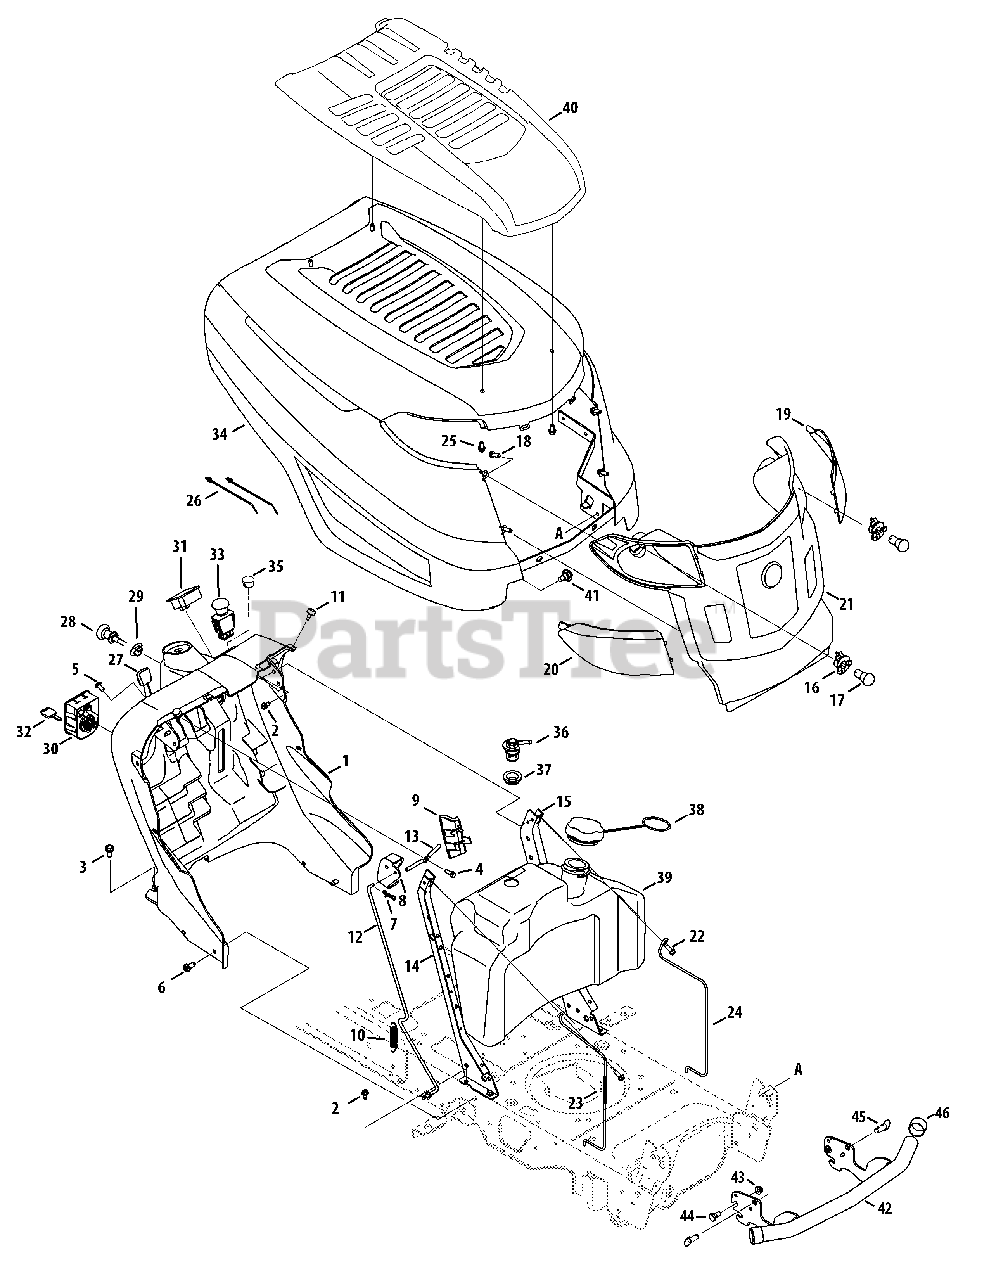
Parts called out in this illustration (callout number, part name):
1	Dash Panel (Manual PTO)
1	Dash Panel (Elect PTO)
2	Screw, 1/4-20 x .50
3	Hex Wash HD S-Tapp Scr 5/16-18 x .75
4	Hex Bos Scr 1/4 x .75" Lg.
5	Torx Mach. AB-Tapp Scr. 1/4-14 x .625 Lg
6	Screw 5/16-18 x .75
7	Bow Tie Cotter Pin
8	Dash Lever
9	Cruise Cover
10	Extension Spring .500 Dia. x 2.733" Lg.
11	Bumper
12	Control Rod
13	Pivot Rod
14	RH Dash Support Plate
15	LH Dash Support Plate
16	Lamp Socket
18	Screw 1/4 x .75
19	Lens LH
20	Lens RH
21	Grille Style "K"
22	TT Scr. 1/4-20 x .625 Lg.
23	LH Support Rod
24	RH Support Rod
25	Hex Screw 1/4-15 x .50
25	Cable Tie
27	Throttle/Choke Cont. Cable (Single Cyl.)
27	Throttle/Choke Cont. Cable (Kohler Twin) (w/Electric PTO)
28	Choke Cable
29	Choke Plug (Single Cyl.)
30	Module Ignition Switch (Man PTO)
30	Module Ignition Switch (Electric PTO)
31	Systems Ind. Monitor w/Hr. Meter
31	Ammeter Indicator
33	Electric PTO Switch
34	Hood Style "K"
36	Rollover Valve
37	Rubber Grommet
38	Cap-Fuel (w/hoop)
39	Tank Ass’y
40	Hood Scoop
41	Shoulder Screw 5/16-18: .43 x .29
42	Bumper Assembly
43	Hex Lock-Nut 3/8-16 Nylon
44	Shoulder Scr. .498 x .340: 3/8-16
45	Quick Pin 1/2" dia. x 0.50
46	Bumper Cap
